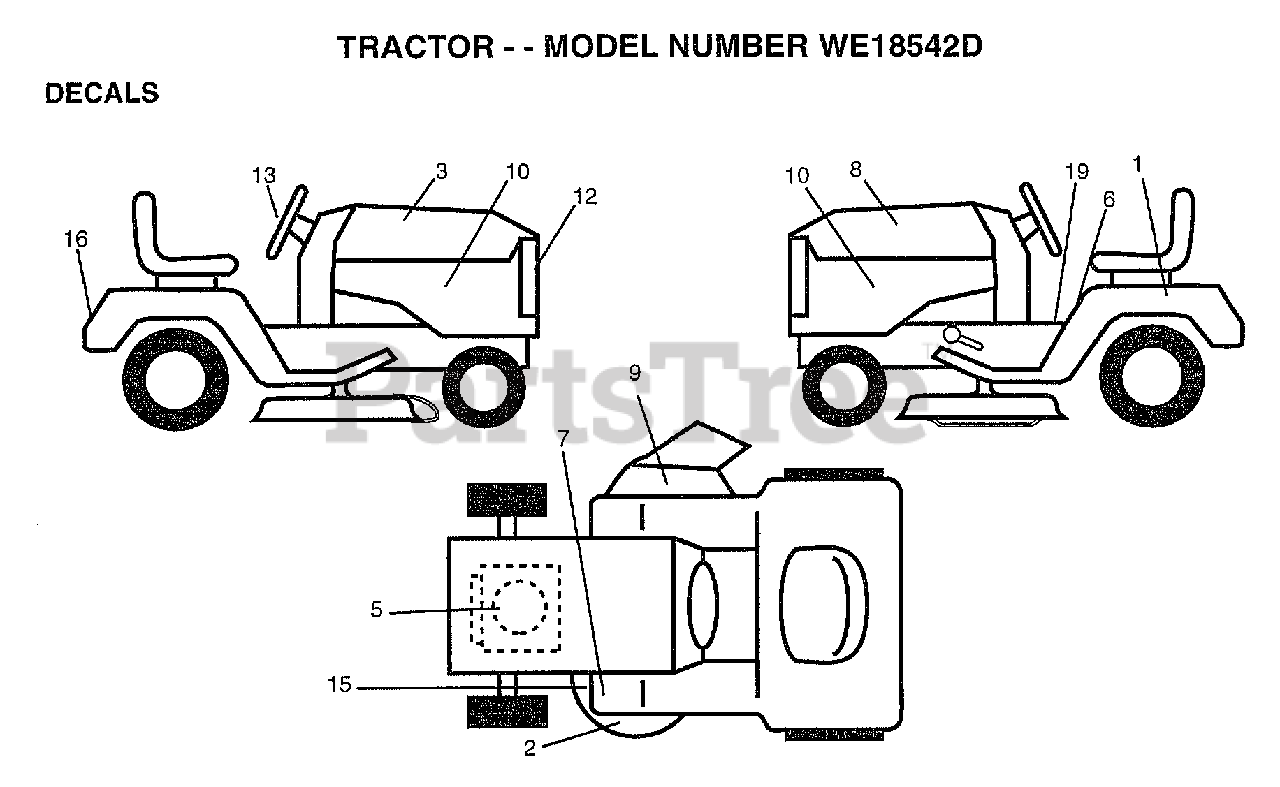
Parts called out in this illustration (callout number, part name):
1	DECAL.BATRY.3-3908
2	DECAL, DECK GRASSEATER
3	DECAL.HOOD.RH.
5	DECAL.HP.ENGINE
6	DECAL.CAUT.ENG/FR
7	DECAL T
8	DECAL.HOOD.LH
9	"DECAL, WARNING"
10	DECAL.PNL.SIDE
12	DECAL, GRILLE LENS
13	DECAL, INS STRG WH
15	"DECAL-SCHEM,BELT"
16	DECAL.FENDER.LOGO
19	"DECAL.OPER,SDL"
